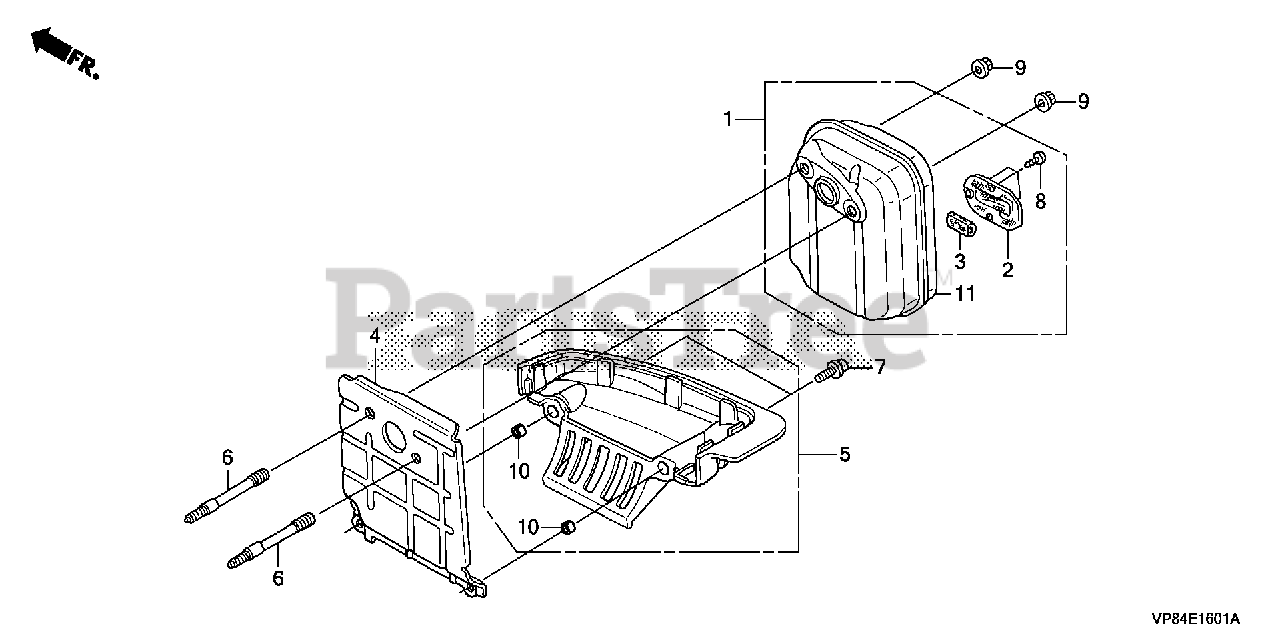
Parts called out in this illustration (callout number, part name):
1	MUFFLER (ARRESTER)
2	ARRESTER, SPARK
3	FILTER, EX.
4	GUIDE, AIR
5	GUIDE, AIR (LOWER)
6	BOLT, STUD (5X56.5)
7	BOLT, SOCKET (5X16)
8	SCREW, TAPPING (4X6) (TO INSTALL OPTIONAL SPARK ARRESTER)
9	NUT, SELF-LOCK (5MM)
10	COLLAR A, HEAD COVER
